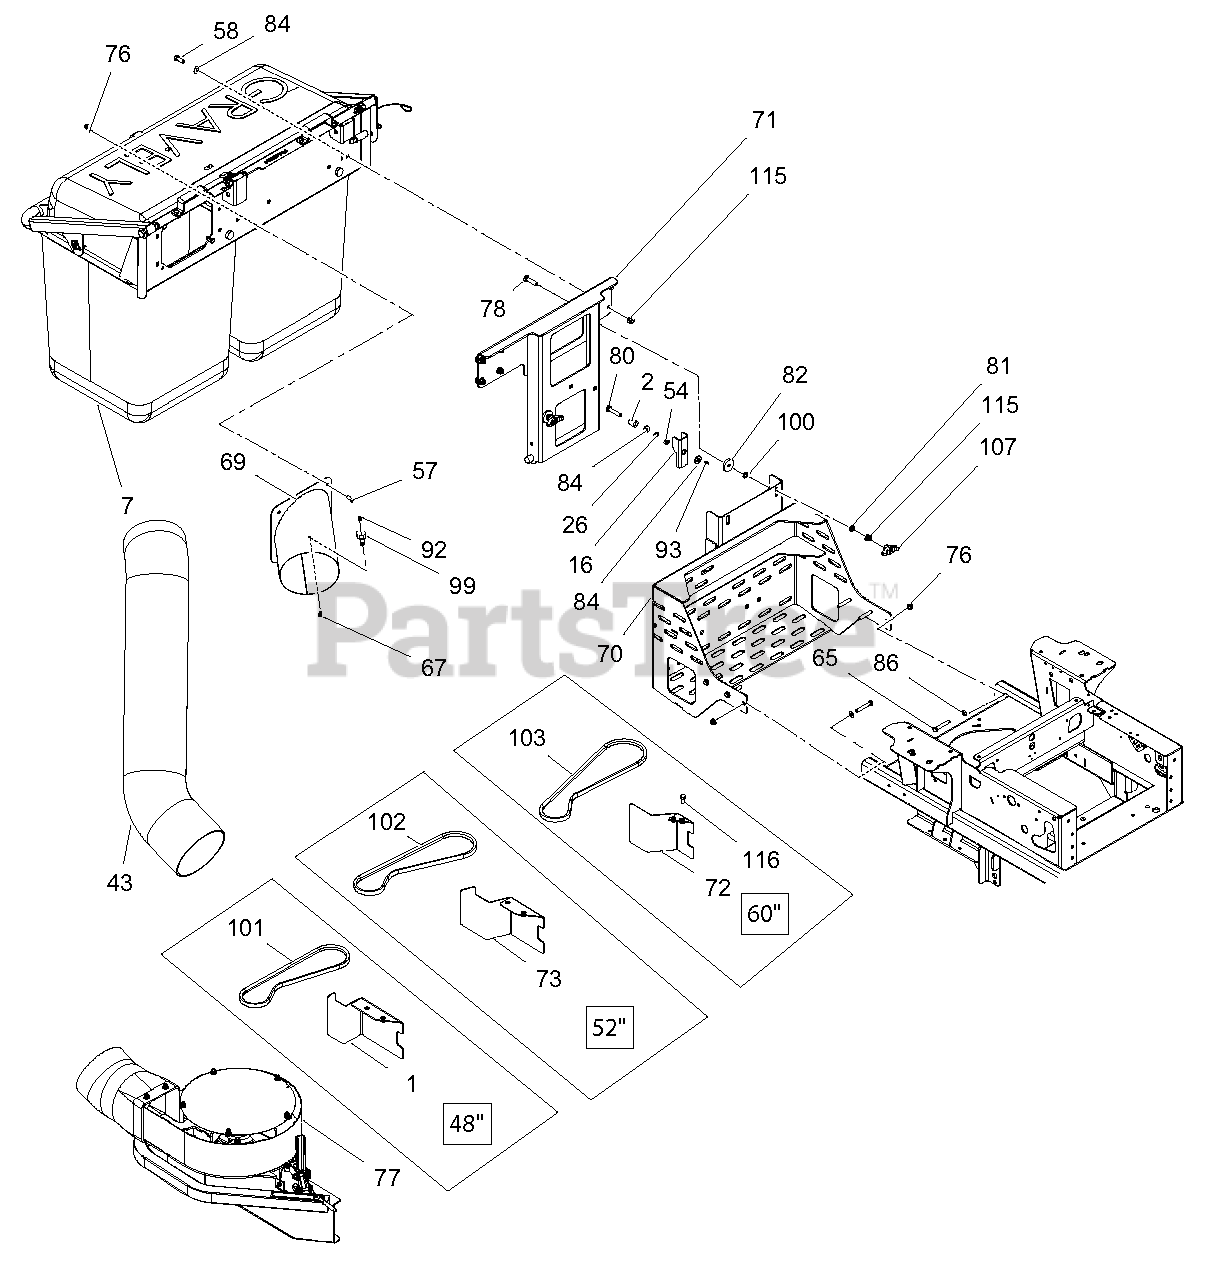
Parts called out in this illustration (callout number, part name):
1	WLDMT, 48" FRONT BLOWER BAFFLE-BLACK
2	BSHG, SPCR .41 X .75 X .88 PM
7	HUMBOLT 2-BAG (8BU) RECEPTACLE
16	LATCH, BAGGER UPPER MOUNT-BLACK
26	WAVE WASHER .640 X .875 X .125 FH
43	HOSE, BAGGER 7 X 49
54	BSHG, SLV .377 X .624 X .235
57	BLT-HEX .31-18 X .75 GR5 YWZC
58	BLT-HEX .38-16 X 1.00 GR5 YWZC
65	BLT-HEX .31-18 X 2.25 GR5 YWZC
67	SCR-MCH 10-24 X .50 HWH YWZC
69	WLDMT, BAGGER INLET TUBE-BLACK
70	WLDMT, 2-BAG LOWER MOUNTING BLACK
71	WLDMT, 2-BAG UPPER MOUNT BLACK
72	WLDMT, 60" FRONT BLOWER BAFFLE BLACK
73	WLDMT, 52" FRONT BLOWER BAFFLE BLACK
76	NUT LK NYL FLG .31-18 YWZC
77	BLOWER ASSEMBLY, SERVICE
78	BLT-RDHDSQNK .38-16 X 1.75 GBYZ
80	BLT-RDHDSQNK .38-16 X 2.00 GR5
81	WSHR-LK .38 X .115 HVY YWZC
82	WASHER FL STL .406 X 1.50 X .245 YWZC
84	WSHR FL STL .438 X 1.00 X .083 YWZC
86	WSHR FL STL .344 X .688 X .065 YWZC
92	NUT LK NYL #10-24 YWZC
93	NUT, LK TOP FLG .38-16 YWZC
99	LATCH, THUMB
101	V-BELT, 4L WRAPPED CLUTCHING
102	V-BELT, 4L WRAPPED CLUTCHING
103	V-BELT, 4L WRAPPED CLUTCHING
107	KNOB, WING .38-16 UNC NYL/TALC
115	NUT-LK-NYL-FLG .38-16 YWZC
116	BLT-HEX .38-16 X .75 GR5 YWZC
